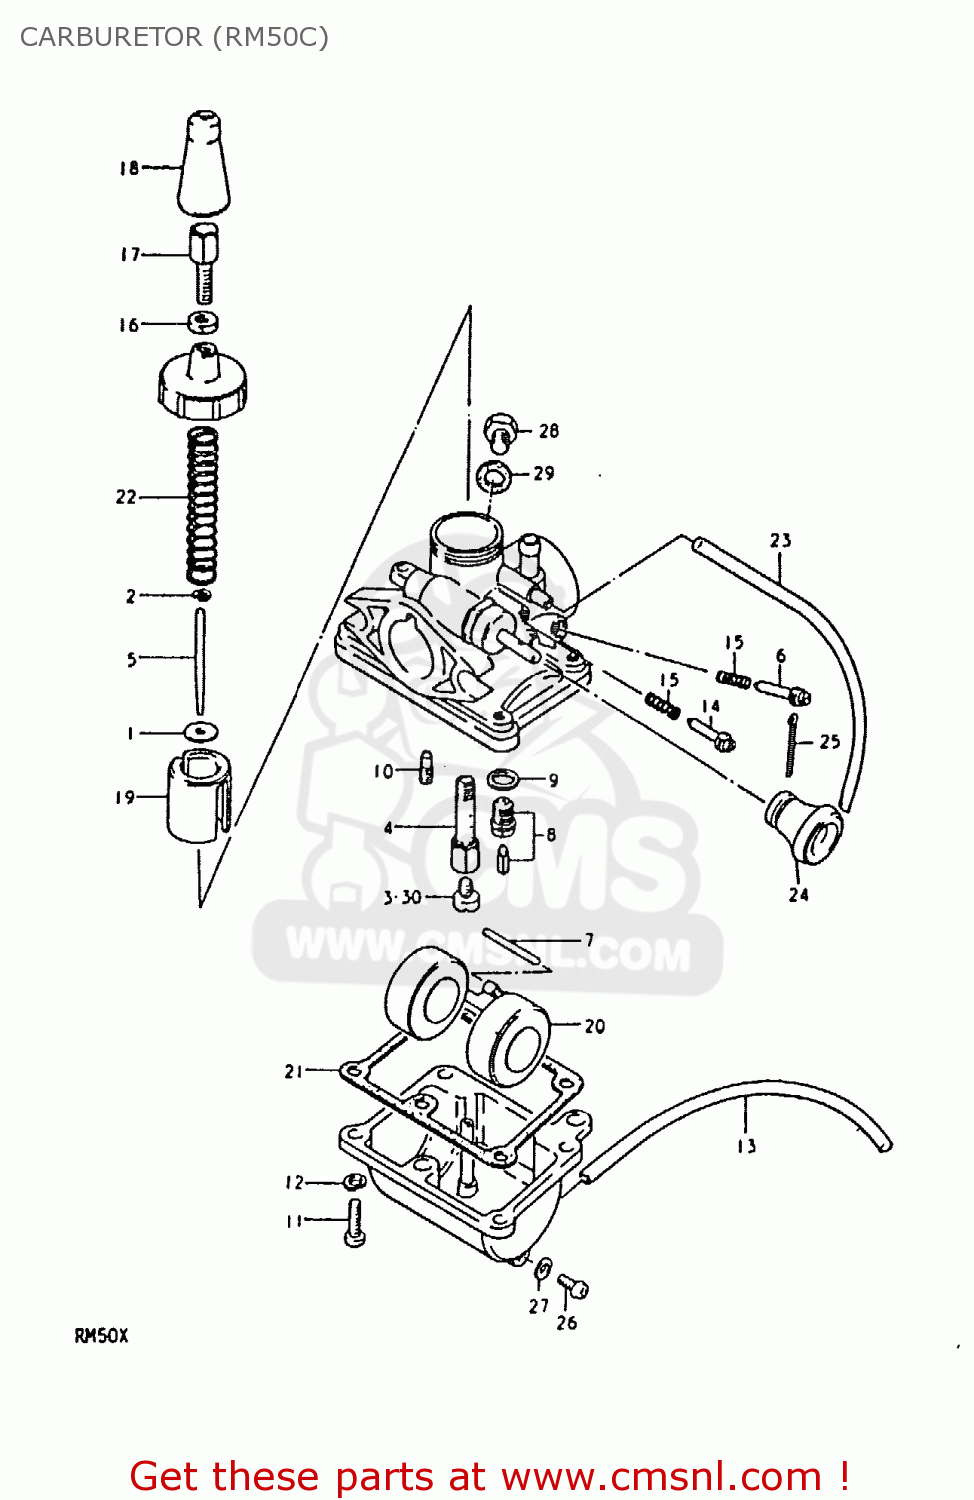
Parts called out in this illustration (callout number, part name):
1	PLATE,THROTTLE VALVE
2	CLIP,NEEDLE
3	JET,MAIN
4	JET,NEEDLE
5	NEEDLE JET
6	SCREW,AIR
7	PIN,FLOAT
8	VALVE ASSEMBLY,NEEDLE
9	GASKET,NEEDLE VALVE (NAS)
10	JET,PILOT
11	SCREW
12	LOCK WASHER
13	HOSE
14	SCREW,THROTTLE STOP
15	SPRING
16	NUT
17	ADJUSTER,CABLE
18	CAP
19	VALVE,THROTTLE
20	FLOAT
21	GASKET,FLOAT CHAMBER (NAS)
22	SPRING,THROTTLE VALVE
23	HOSE
24	LEVER
25	COTTER PIN
26	SCREW
27	GASKET
28	BOLT
29	GASKET,THRO VALVE INSPECTION (NAS)
30	JET
